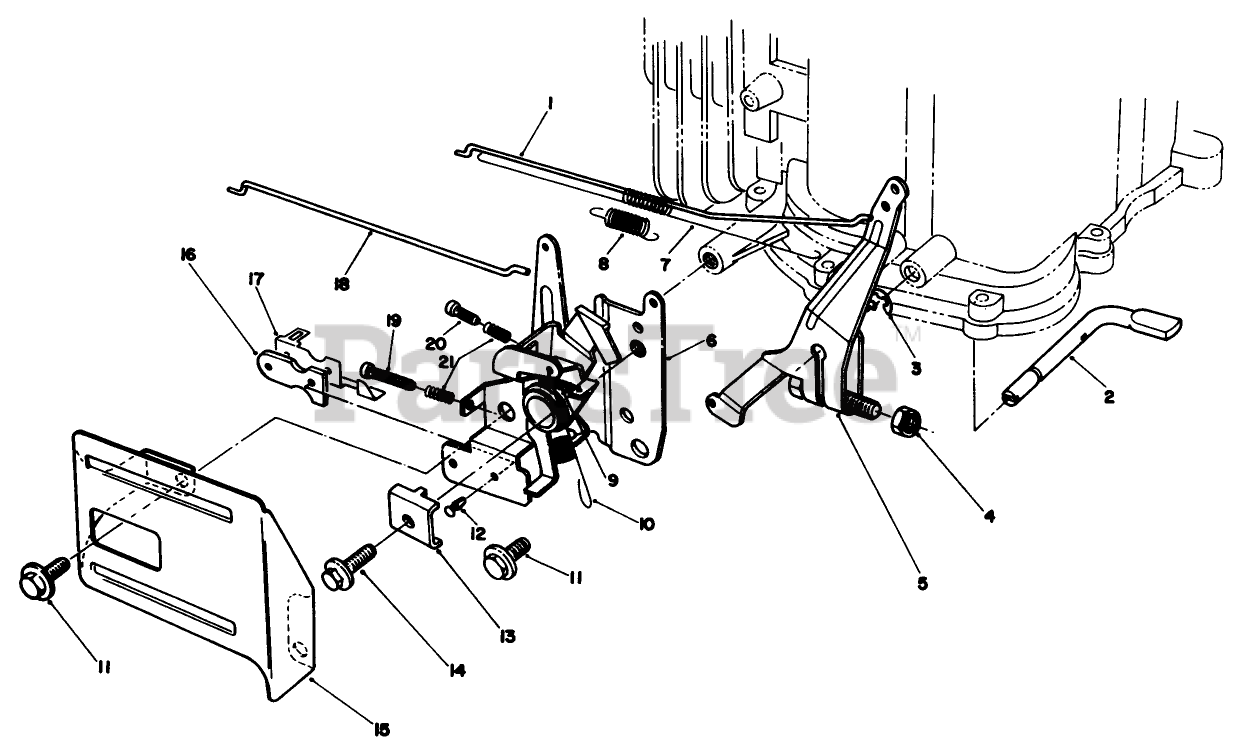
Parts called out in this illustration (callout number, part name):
7	SPRING
8	SPRING
10	SPRING
12	RIVET
13	CLAMP-CABLE
15	THROTTLE GUARD *
16	INSULATOR-KILL SWITCH
17	TERMINAL-KILL SWITCH
21	SPRING
22	SCREW
23	CLAMP F/W ENGINE
